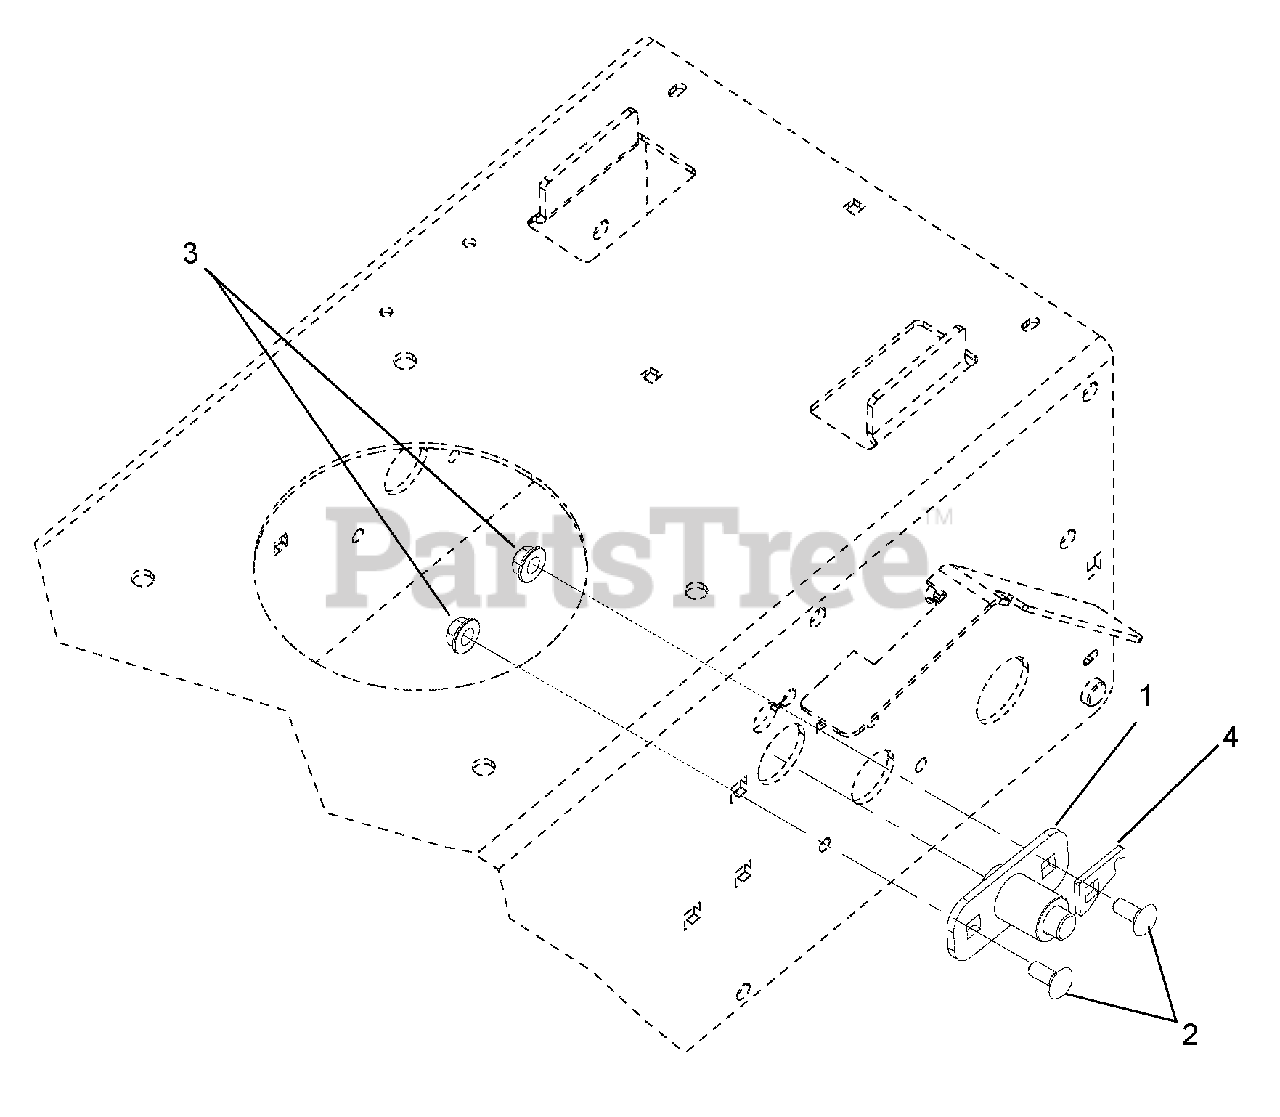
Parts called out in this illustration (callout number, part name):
1	Kit, Pin Brake
2	Bolt, Round Head Square Neck .38-16 x 1.25 Grade 5
3	Nut, Flange .375-16
4	Extender, Spring (SN 000101 - 000609)
